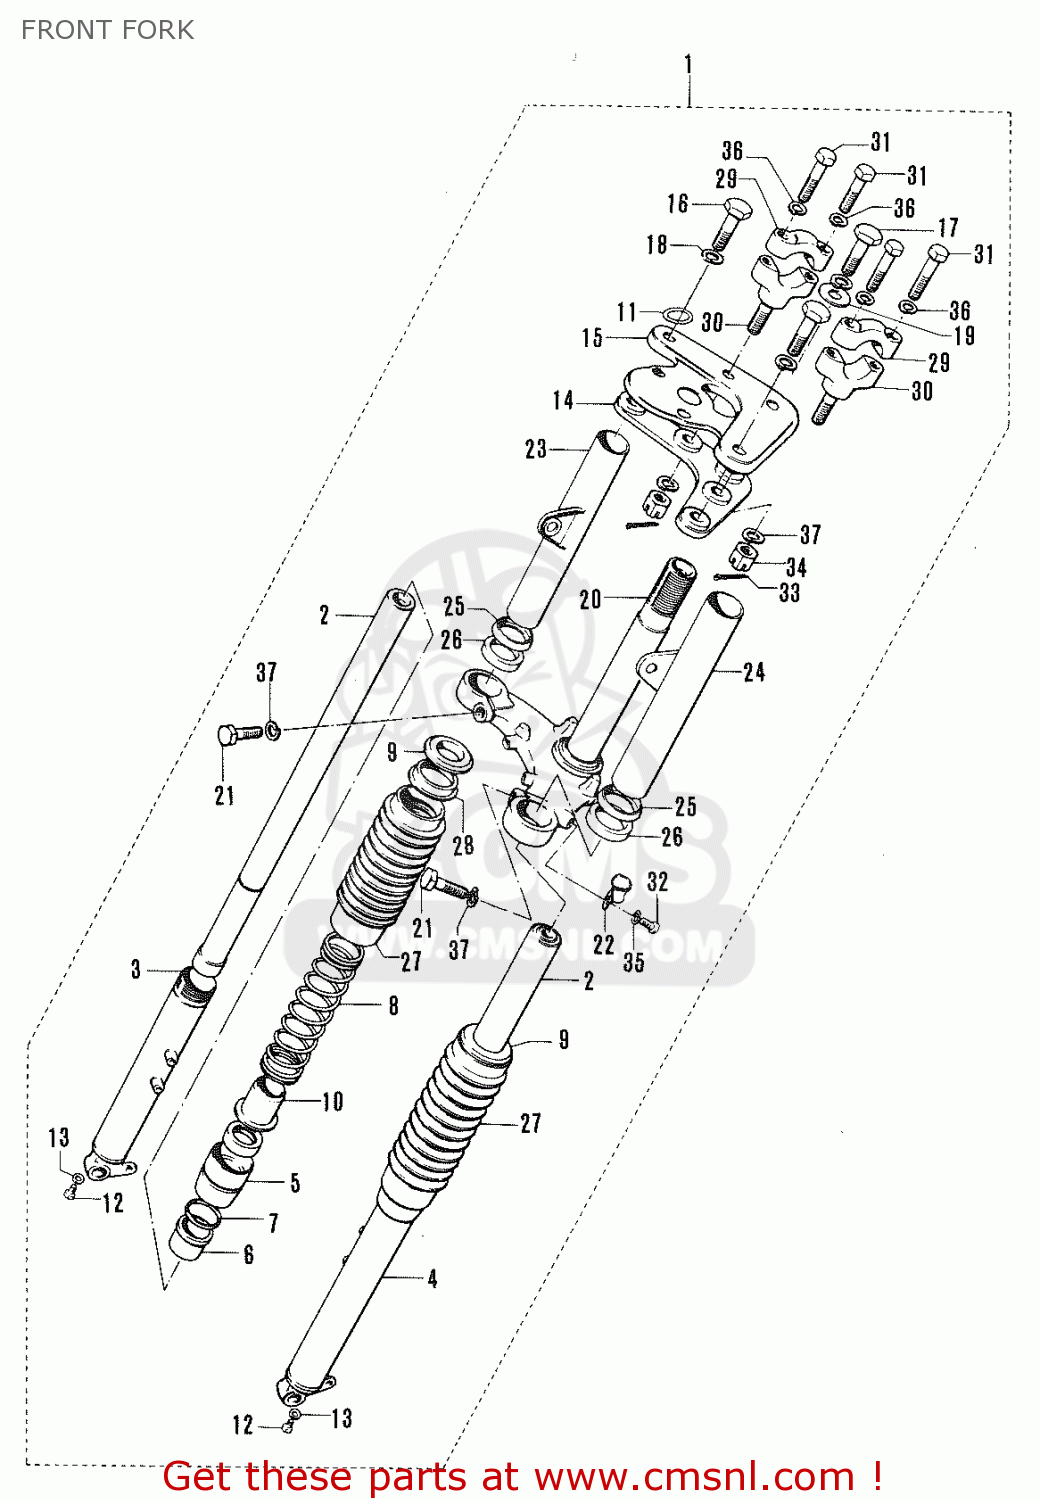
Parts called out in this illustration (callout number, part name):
1	FRONT FORK ASS'Y
2	TUBE,FORK,INNER
3	TUBE,OUTER,RIGHT
4	TUBE,OUTER,LEFT
5	NUT,FORK OUTER TUBE
6	BUSHING,GUIDE
7	O RING,OIL SEAL LWR
8	SPRING,FRONT FORK
9	SEAT,SPRING
10	DUST SEAL,FRONT FORK
11	FORK FITTING BOLT "O" RING
12	OIL DRAIN PLUG
13	GASKET,DRAIN,PLUG (NAS)
14	HEAD,STEERING STEM
15	METER BRACKET
16	CAP,FORK INNER TUBE
17	BOLT,STEERING STEM HEAD
18	WASHER
19	WASHER
20	STEM,STEERING
21	BOLT,FORK INNER TUBE F
22	CLIP,BRAKE CABLE
23	BRACKET COMP,HEADLAMP
24	BRACKET,HEADLAMP,LEFT
25	SEAT,HEADLAMP BRACKET
26	CUSHION,HEADLAMP BRACKET
27	BOOT
28	BAND,FRONT FORK COVER
29	HOLDER,HANDLEBAR
30	HANDLEBAR LOWER HOLDER
31	BOLT
32	SCREW, CENTER SHAFT
33	PIN 25X20
34	NUT
35	LOCK WASHER
36	LOCK WASHER
37	LOCK WASHER
